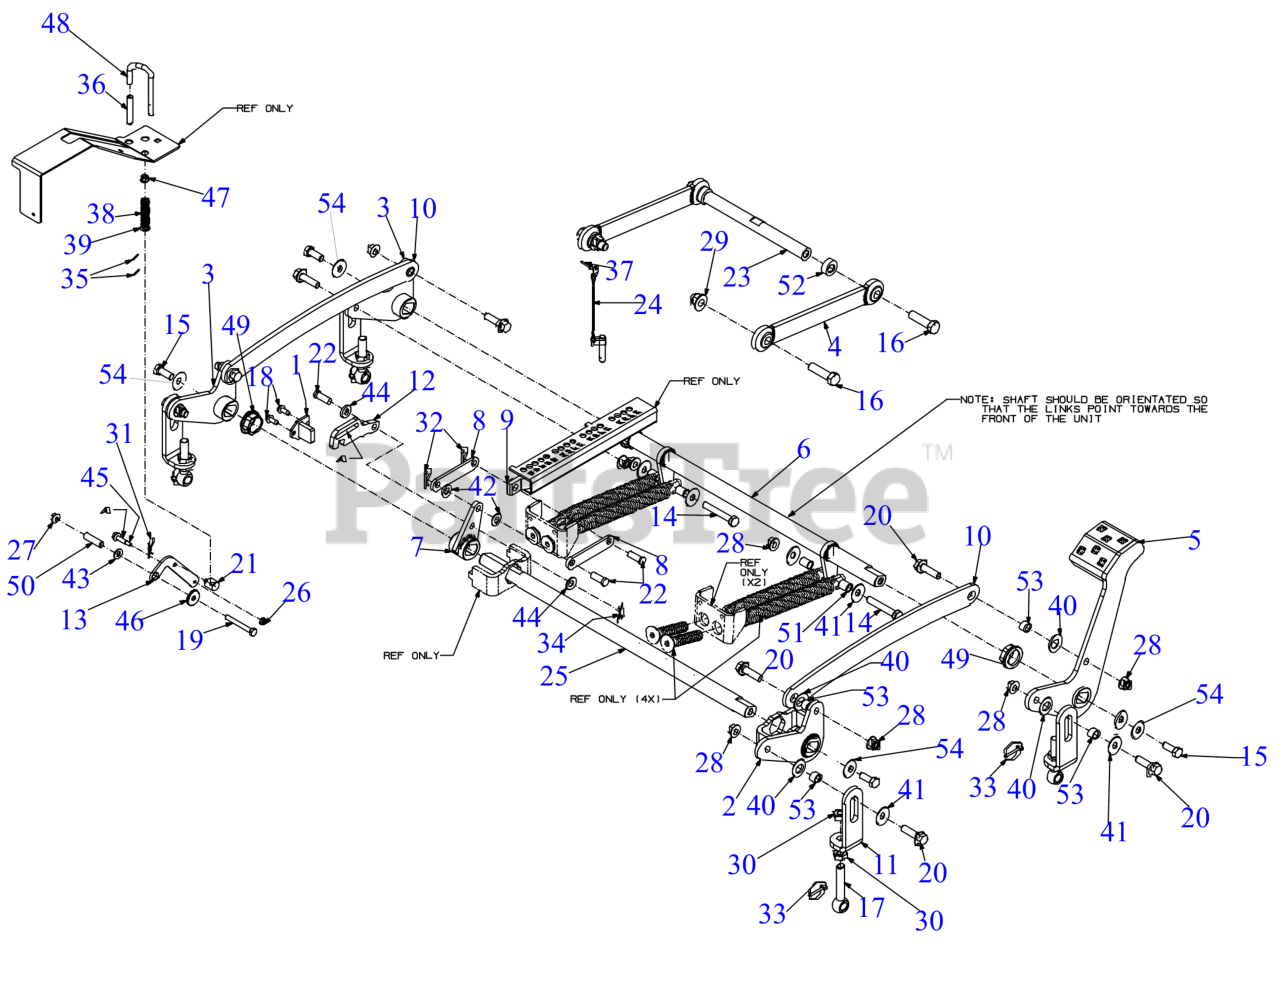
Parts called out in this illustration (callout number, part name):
1	LIFT LOCK MOUNT
6	FRONT DECK LIFT SHAFT
7	DECK LIFT HUB ASSEMBLY (LH)
8	DECK LIFT INDEX LINK
9	LIFT INDEX SLIDER ARM
12	LOCK LATCH BRACKET
13	PIVOT LOCKOUT LINK
14	SCREW-HEX 1/2-13 x 3.00
15	SCREW 1/2-13 x 1.25 GR5
16	SCREW 5/8-11 x 2.25 GR5
17	EYE BOLT 5/8-11 x 3.63
18	SCREW 5/16-18 x .750
19	SCREW 3/8-16 x 2.75 GR5
20	FLANGE BOLT 1/2-13:1.75:GR5
21	BRAKE ROD FERRULE
22	CLEVIS PIN .500 x 1.25
23	FRONT LIFT SHAFT
24	DETENT PIN
25	LIFT SHAFT 1.25 DIA
26	FLANGE LOCK NUT
29	FLANGE LOCK NUT
30	HEX JAM NUT
31	INTERNAL COTTER PIN
32	COTTER PIN
33	LYNCH PIN .1875
34	PIN:COTTER
35	COTTER PIN-3/32 DIA x .75
37	FULL TUBULAR RIVET
38	COMPRESSION SPRING .656 ODX 2.445"
39	FLAT WASHER
40	FLAT WASHER .760ID X1.49OD x .06
41	FLAT WASHER
42	FLAT WASHER .510X.995
43	FLAT WASHER.40 ID
44	FLAT WASHER
45	SHOULDER SCREW
46	SHOULDER SPACER
47	BUSHING .380 ID
48	DECK LOCK OUT ROD
49	FLANGE BEARING
51	SPACER 0.535 x 0.68 x 0.83
52	SPACER .635X1.25X.445
54	FLAT WASHER .53"x2.125"x.25"
